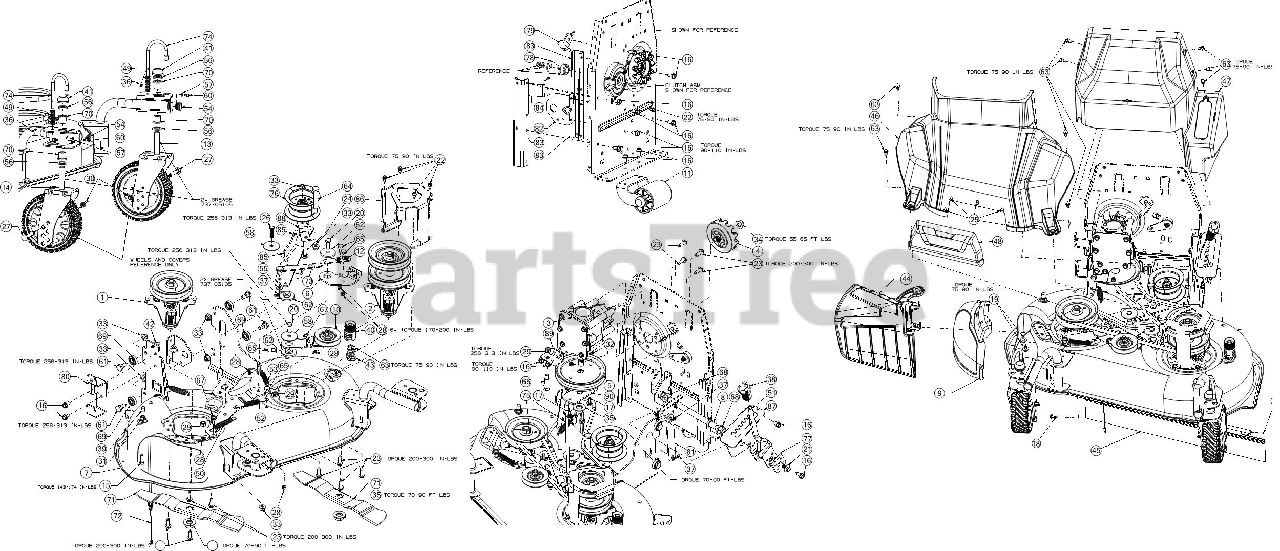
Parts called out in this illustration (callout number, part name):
1	SPINDLE ASSEMBLY
2	SPINDLE ASSEMBLY
3	ANGLE GEARBOX
4	DOG CLUTCH ASSEMBLY
5	DRIVE PULLEY 6.03 DIA
6	DECK BRACKET ASSEMBLY
8	DECK LIFT ASSEMBLY
9	28" MULCH PLUG ASSEMBLY
10	PULLEY BRACKET ASSEMBLY
11	ROLLER BRACKET ASSEMBLY
12	BRAKE WELD ASSEMBLY
13	CASTER BRACKET ASSEMBLY (LH)
14	CASTER BRACKET ASSEMBLY (RH)
15	SCREW 5/16-18 x 1.0 GR5
16	SCREW 5/16-18 x .750
17	SCREW 1/4-20 x .75 GR5
18	SCREW 10-16 x .625
19	SCREW 1/4-20 x .50
20	SCREW 3/8-16 x 1 GR5
21	SCREW 5/16-24 x .750 GR5
22	SCREW 1/4-20 X.500
23	SCREW 5/16-18 x 1.00
24	BOLT 3/8-16X2.25 GR5
25	SCREW 1/4-10 x .750
26	SCREW 3/8-16 x 1.25 GR5
27	CASTER AXLE
28	HEX NUT
31	FLANGE LOCK NUT 5/16-18
32	FLANGE LOCK NUT
35	FLANGE NUT 5/8-18
36	COTTER PIN .072 DIA
37	BOW TIE COTTER PIN 1/4-5/16
38	HANDLE GRIP
40	WATER NOZZLE
42	CABLE RETAINER CLIP
43	DECK WASH NOZZLE
44	CHUTE DEFLECTOR
45	TRAILSHIELD 23.00
46	LOWER COVER DECK 28"
47	UPPER COVER DECK 28"
48	LOWER COVER
49	COMPRESSION SPRING
50	EXTENSION SPRING
51	DECK HEIGHT LEVER
52	EXTENSION SPRING
53	EXTENSION SPRING
55	FLAT WASHER
56	FLAT WASHER
57	FLAT WASHER
58	HUB CAP WASHER .406 x 1.92 x .060
59	GREASE (NOT SERVICEABLE)
60	GREASE FITTING
61	SHOULDER SCREW .498 DIA x .340
62	SHOULDER SPACER
63	SHOULDER SCREW 1/4-20 x .50
64	SHOULDER SCREW
65	SHOULDER SCREW .375X.380:1/4-20
66	SHOULDER SCREW .50
67	SHOULDER SCREW .37
68	FLANGE BEARING
69	BALL BEARING
70	BEARING:FLANGE .631 ID
71	14.20" BLADE (MULCH)
72	DECK CABLE
75	DECK BELT A SEC x 43.10
76	IDLER PULLEY
77	HEIGHT LEVER BRACKET
78	DECK CABLE BRACKET
79	DECK CABLE BRACKET
80	GRASSBAG BRACKET
81	LIFT LINK BRACKET
84	KEEPER BRACKET
85	DRIVE ENGAGEMENT BRACKET
86	BELT KEEPER BRACKET
87	HEIGHT ADJUSTMENT BRACKET
88	KEEPER BRACKET
89	KEEPER BRACKET
90	GEAR BOX SPACER
